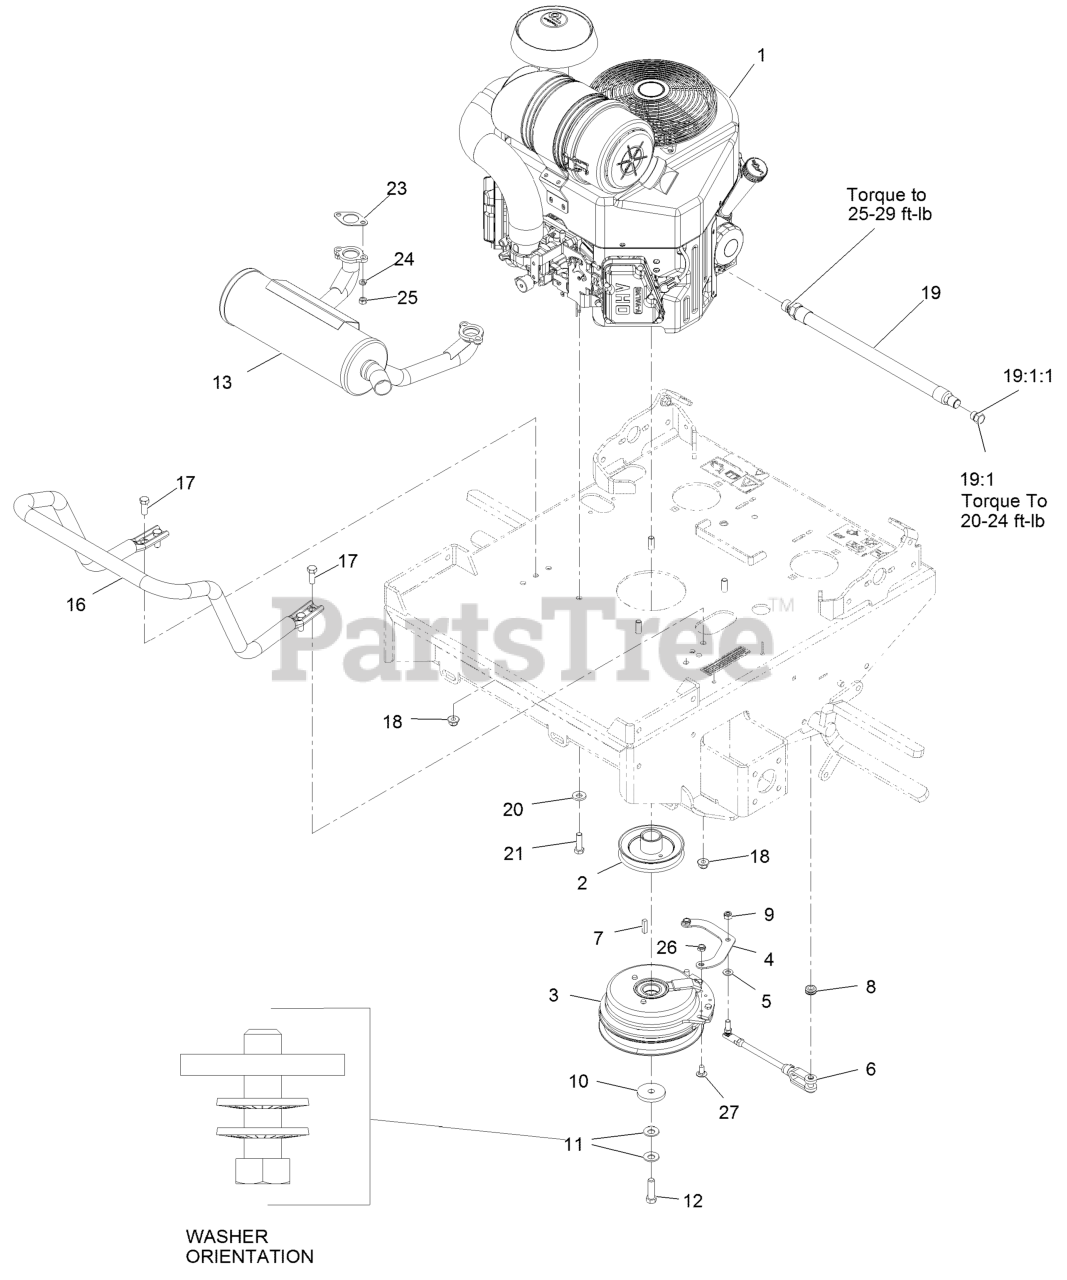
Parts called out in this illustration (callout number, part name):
2	SHEAVE W/ HUB
3	CLUTCH, 200 FT/LBS, 1.13
4	STRAP, CLUTCH
5	WASHER-PLAIN
6	ASM, CLUTCH ANCHOR
7	KEY
8	GROMMET
9	NUT-LOCK
10	WASHER-CLUTCH
11	WASHER-SPRING
12	BOLT-HEX, TAP
13	MUFFLER,HORIZONTAL
16	GUARD-MUFFLER
17	SCREW-HH
18	NUT-HF, NI
19	ASM, ENGINE OIL DRAIN HOS
19:1	PLUG-HH
19:1:1	O-RING
20	WASHER-BELLEVILLE
21	SCREW-HH
23	GASKET-EXHAUST
24	WASHER-LOCK
26	NUT-LOCK, NI
27	SCREW-CARR
